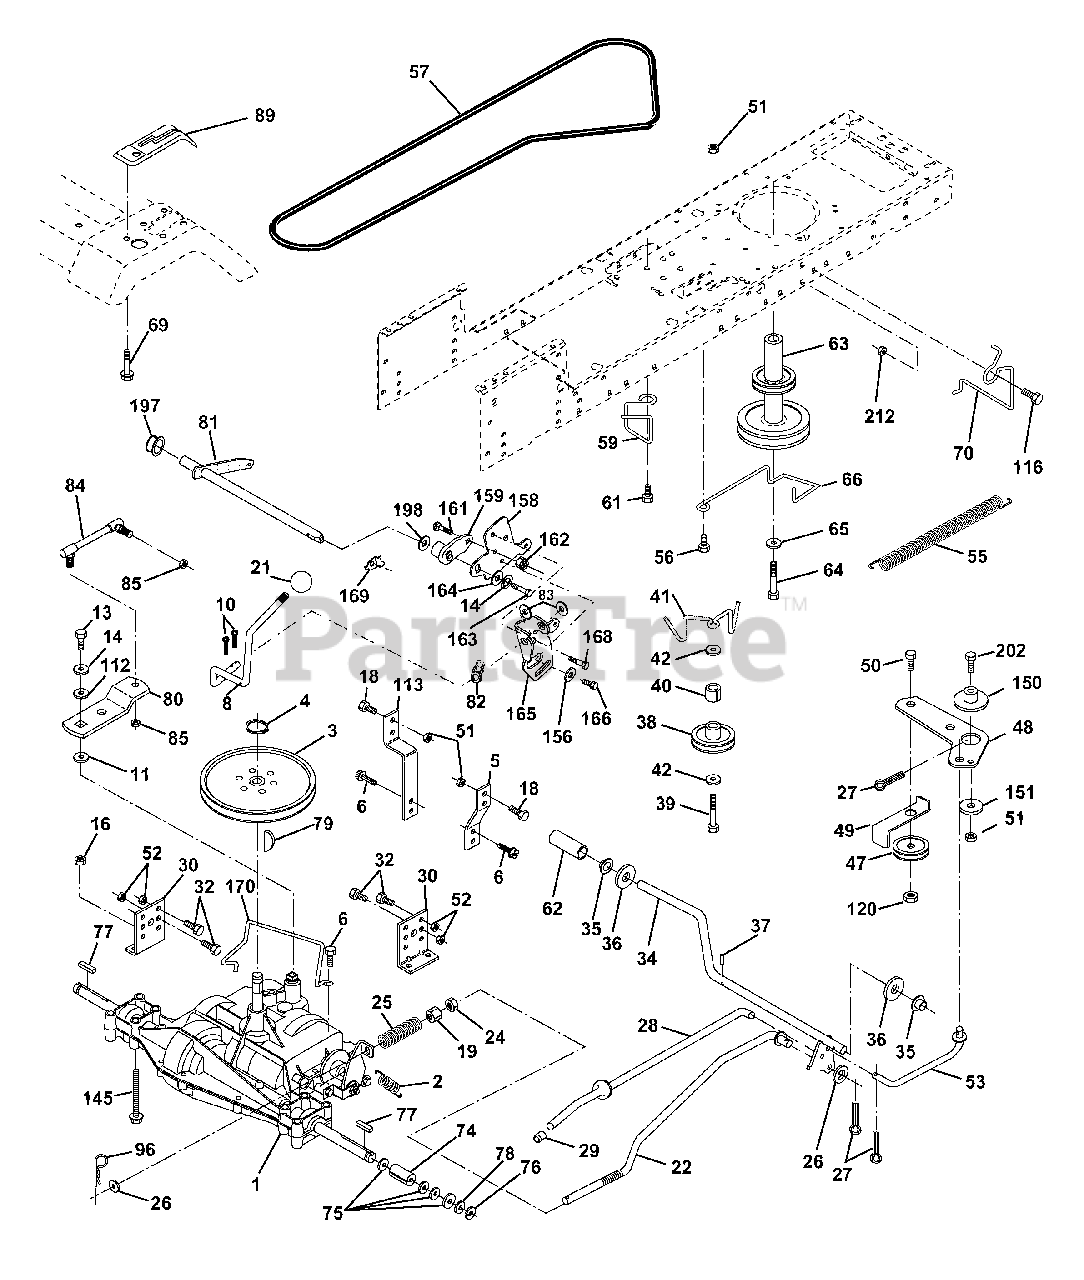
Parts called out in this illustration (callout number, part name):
2	Spring Return Brake T/a Zinc
3	Pulley Transaxle 18" tires
4	Ring Retainer # 5100-62
5	Strap Torque 30 Degrees
6	Screw 5/16-18 X 3/4
8	Rod Shift Fender Adjust Lt
10	Pin Cotter 1/8 X 1 Cad
11	Washer Plate Shf 388 Sq Hole
13	Bolt 1/4-28 Unf Gr 8 W/Patch
14	Washer Lock Hvy Helical
16	Nut Lock Hex w/ins 5/16-18
18	Bolt, Fin Hex 3/8-16 UNC x 1 Gr. 5
19	Nut Lock 3/8-16 Unc
21	Knob
22	Rod Brake Blk Zinc 26 840
24	Nut Hex Jam 3/8-16 Unc
25	Spring Rod Brake 2 00 Zinc
26	Washer 13/32 X 13/16 X 16 Ga
27	Pin Cotter 1/8 X 3/4 Cad
28	Rod Brake Parking LT/YT
29	Cap Brake Parking
30	Bracket Mtg Transaxle
32	Bolt Hex Hd 5/16-18unc X 3/4
34	Shaft Asm Pedal Foot
35	Bearing Nylon Blk 629 Id
36	Washer 21/32 X 1 X 16 Ga
37	Pin Roll 3/16 X 1"
38	Pulley Composite Flat
39	Bolt Fin Hex 3/8-16unc X 2-3/4
40	Spacer Split
41	Keeper Belt Flat Idler
42	Washer 13/32 X 13/16 X 12 Ga
47	Pulley Idler V Groove Plastic
48	Bellcrank Asm
49	Retainer Belt Style Spring
50	Bolt Hex Hd 3/8-16unc X 1-1/2
51	Nut Crownlock 3/8-16 Unc
52	Nut Crownlock 5/16-18 Unc
53	Link Clutch
55	Spring Return Clutch 6 75
56	Screw 3/8-16 x 1.0
57	V-Belt Ground Drive 95 25
59	Keeper Belt Span Ctr
61	Screw 3/8-16x.75
62	Cover Pedal Blk Round
63	Engine Pulley LT/YT
64	Bolt Hex
65	Washer Lock Hvy Hlcl Spr 7/16
66	Keeper Belt Engine Foolproof
69	Screw Hex wsh Hi Lo 1/4 x 1/2 unc
70	Guide Belt Mower Drive RH
74	Spacer Axle
75	Washer 25/32 X 1 1/4 X 16 Ga
76	E-ring #5133-75
77	Key Square 2 0 X 1845/ 1865
78	Washer 25/32 X 1-5/8 X 16 Ga
79	Key Woodruff #9 3/16 x 3/4
80	Arm Shift
81	Shaft Asm Cross Tapered PMST/20
82	Spring Torsion T/a
83	Washer 17/32 X 3/4 X 16 Ga
84	Link Transaxle PMST/20" Zinc
85	Nut Lock Center 1/4 - 28 FNTHD
89	Console Shift STLT
96	Retainer Spring 1"
112	Washer 9/32 x 3/4 x 10 Ga.
113	Strap Torque LT
116	Bolt Rdhd Sq Neck 3/8-16 x 1
120	Nut Lock Flg. 3/8-16
145	Bolt Hex Flghd 5/16-18 Gr. 5
150	Spacer Retainer
151	Washer 13/32 x 2 x 10
156	Washer Srrted 5/16ID x 1.125
158	Bracket Shift Mount
159	Hub Tapered Flange Shift Lt
161	Bolt Rdhd Sqnk 1/4-20 x 3/4 Gr
162	Nut Crownlock 1/4-20 Unc
163	Bolt Hex Fin 1/4-20 Unc x 1 Gr 5
164	Washer 5/8 x .281 x 10 Ga
165	Bracket Pivot Lever
166	Screw 5/16-18 x 5/8
168	Bolt Shoulder 5/16-18 x .561
169	Plate Fastening
170	Keeper Belt Transaxle Pmst/Dana
197	Nyliner Snap-In
198	Washer Nyliner
202	Bolt Carr Sh 3/8-16 x 1-1/2 Gr. 5
212	Nut Hex Flg Lock
